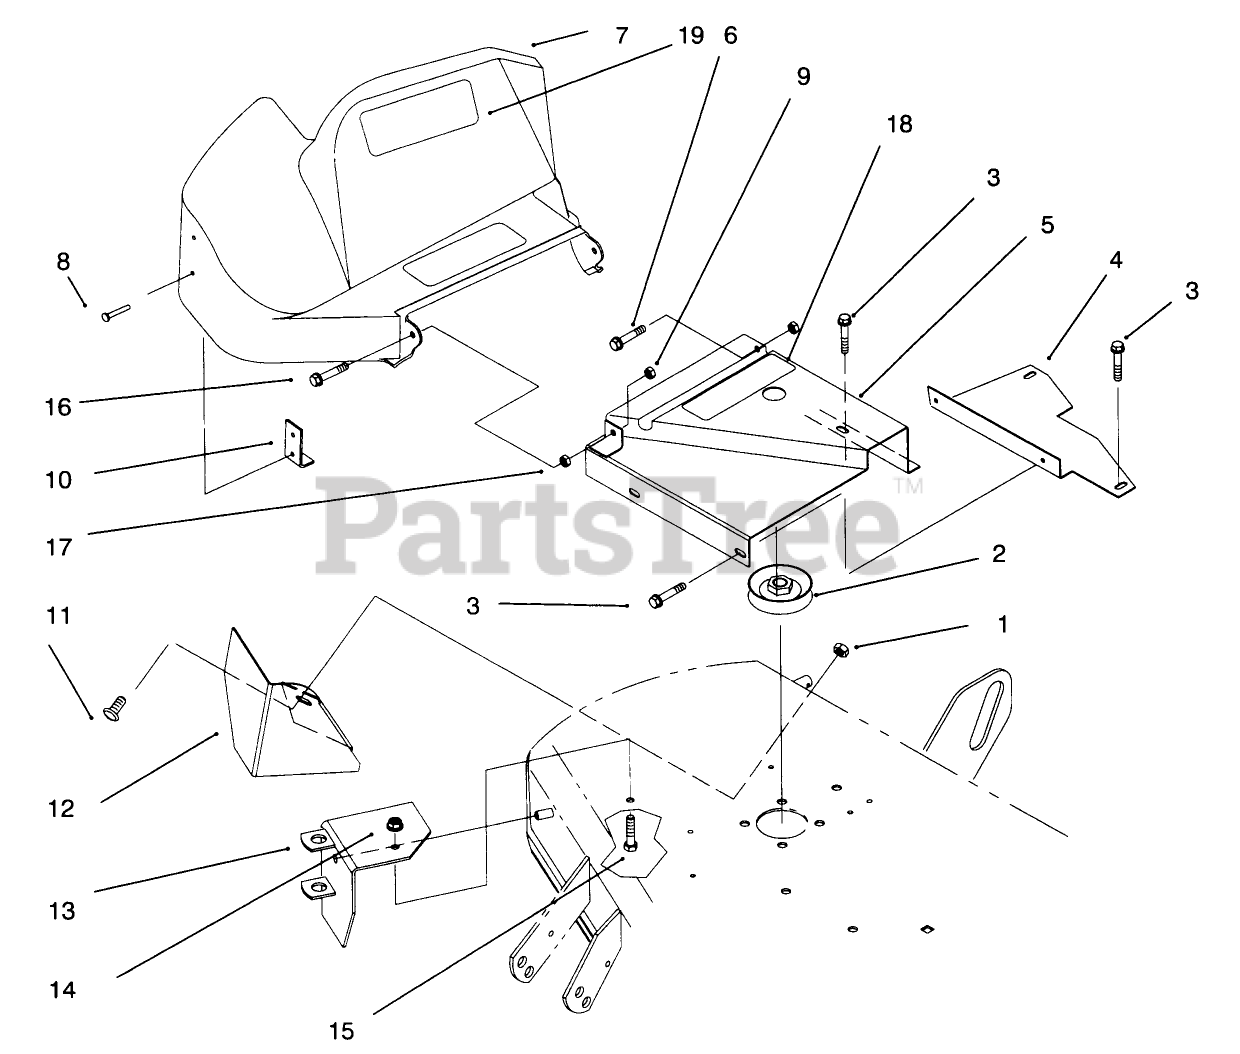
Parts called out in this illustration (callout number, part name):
1	NUT-LOCK, NI
2	42" Y PULLEY
3	SCREW-HWH
4	42" ADAPTOR SHIELD B
5	Inner Shield Asm. (Incl. Ref. #18)
6	SCREW-HH
7	SHIELD-BELT
8	RIVET-POP
9	NUT-LOCK, NI
10	BRACKET-SUPPORT, SHIELD
11	SCREW-CARR
12	42" DEFLECTOR B
13	PIVOT SUPPORT ASM
14	NUT-HF
15	SCREW-HH
16	SCREW-HH
17	NUT-HEX
18	DECAL - DANGER
19	DECAL - DANGER
